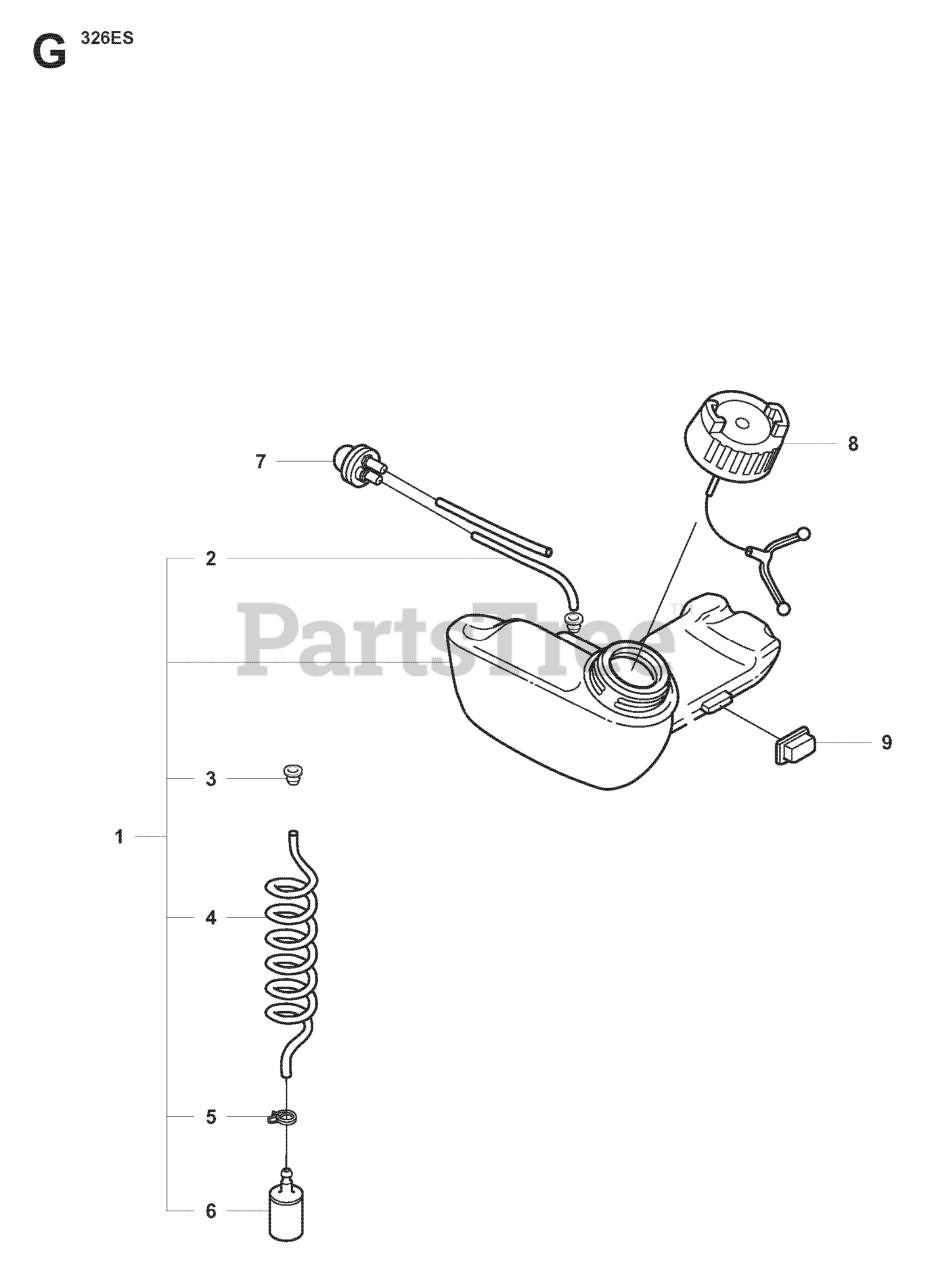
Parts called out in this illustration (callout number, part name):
2	HOSE.FUEL L=102
3	FUEL TANK BUSHING
4	FUEL HOSE
5	HOSE CLAMP
6	RP FUEL FILTER
7	AIR PURGE BUBBLE
8	%FUEL CAP
